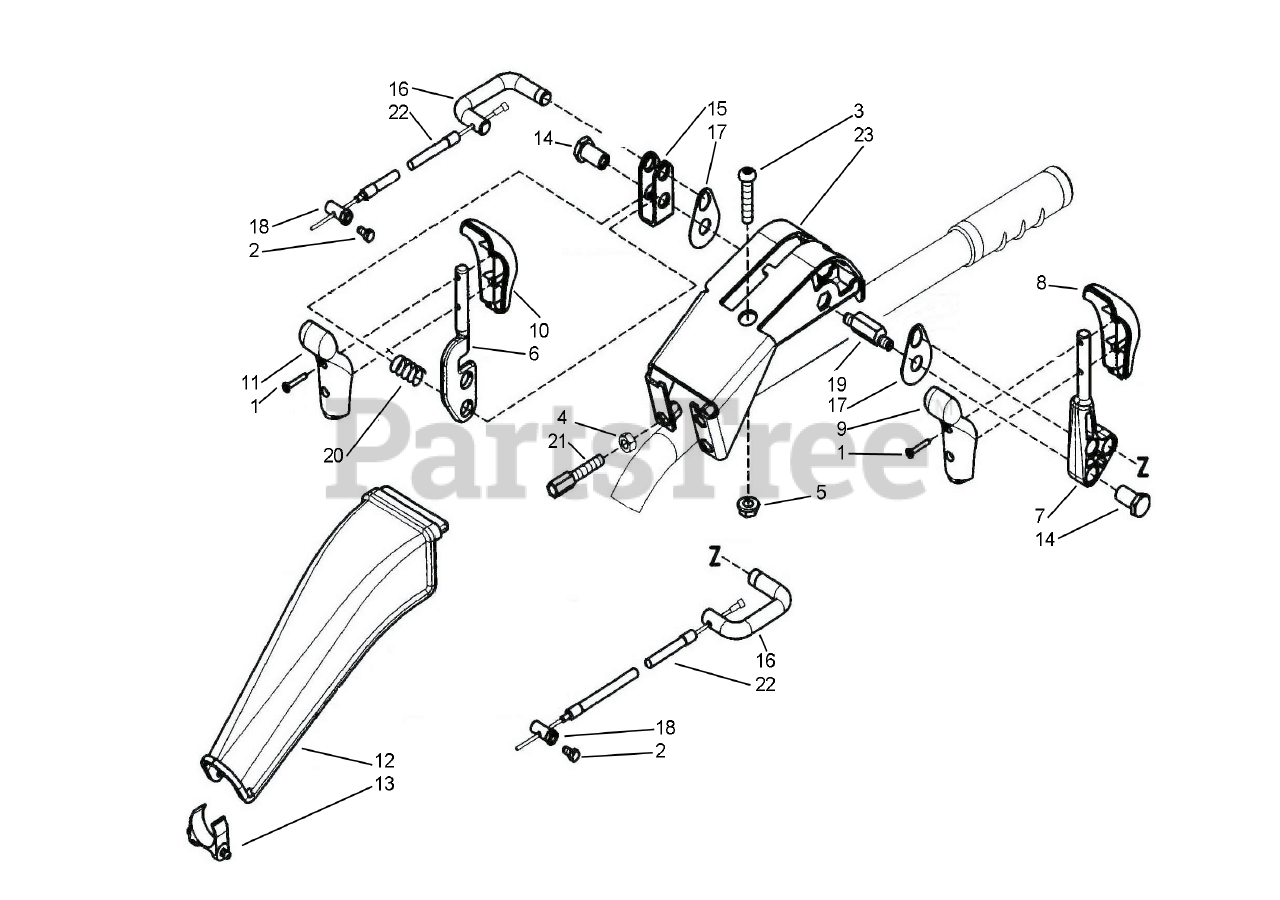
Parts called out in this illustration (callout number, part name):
1	SCREW 5X26
2	CAP SCREW, M6X16
3	SCREW
7	LEVER
8	UPPER HANDLE HALF, BLACK
9	LOWER HANDLE HALF, BLACK
10	UPPER HANDLE HALF, RED
11	LOWER HANDLE HALF, RED
12	COVER
13	CROSS PIECE
14	BUSHING, REVERSE LEVER
16	ANCHOR
17	PLATE, SMALL
18	SCREW, CLAMPING
20	SPRING
21	ADJUSTER
22	CABLE & SHEATH, REVERSE & DIFFERENTIAL
23	SUPPORT
